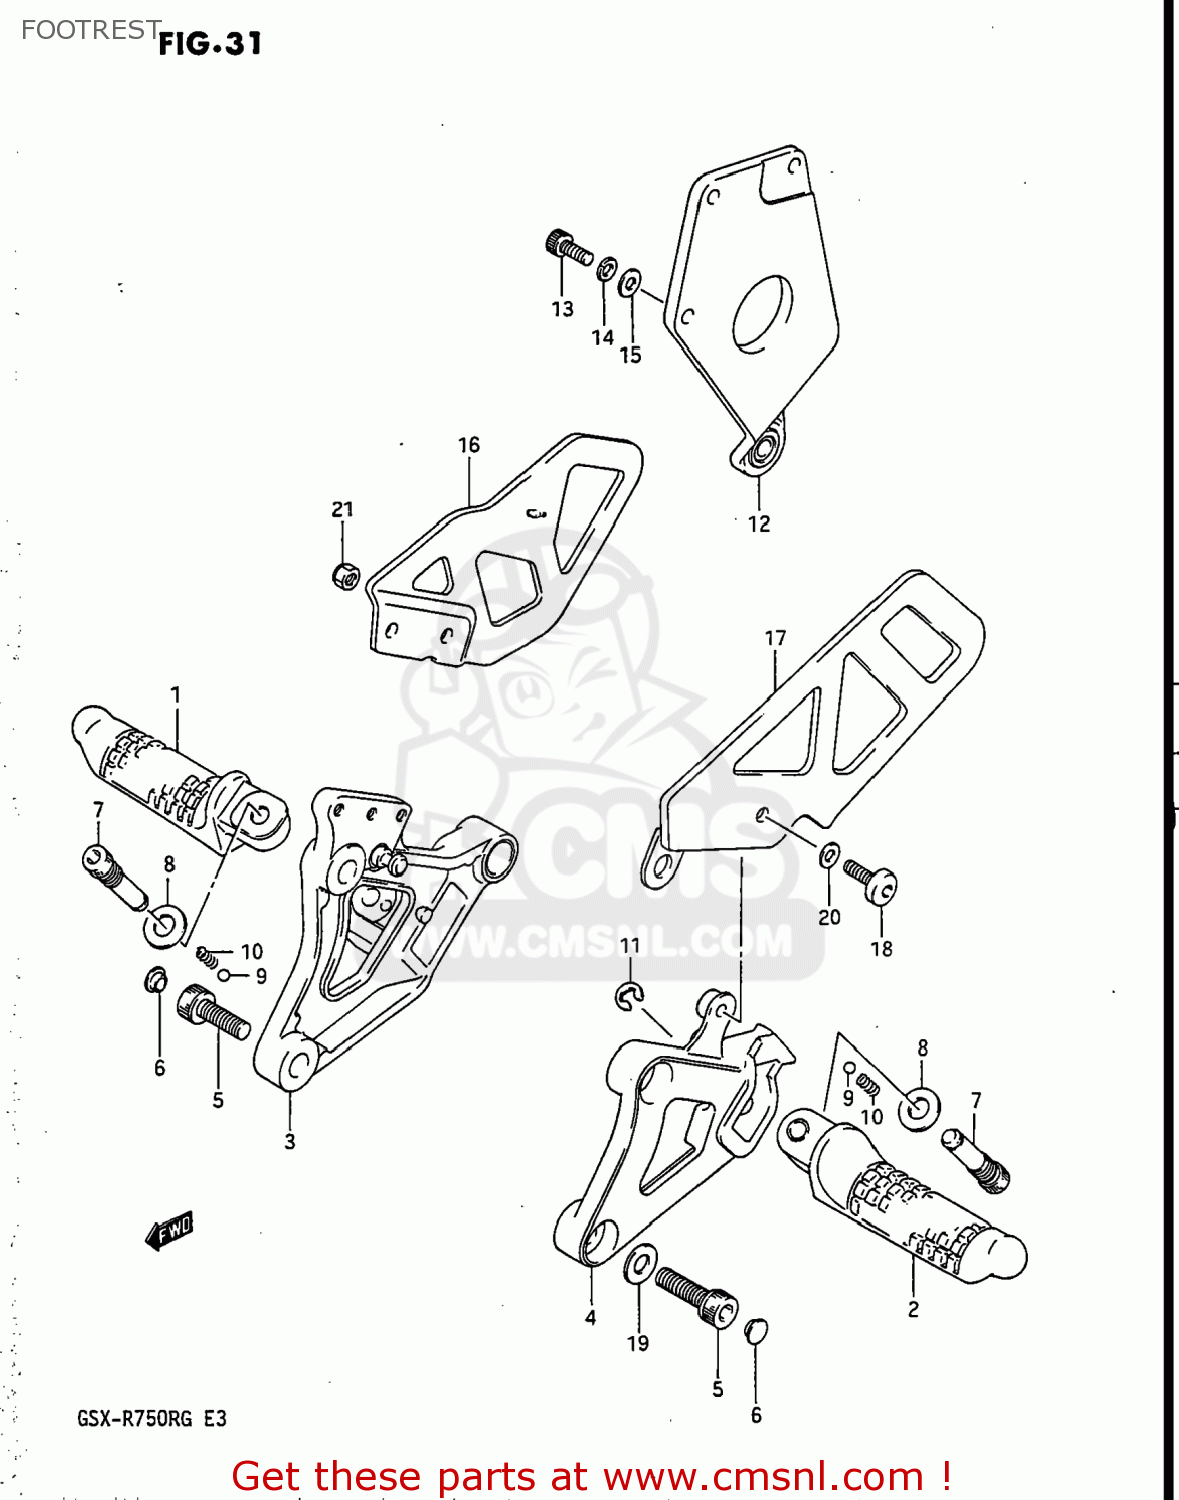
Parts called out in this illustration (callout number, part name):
1	FOOTREST ASSEMBLY,FRONT,RIGHT
2	FOOTREST ASSEMBLY,FRONT,LEFT
3	BRACKET,FOOTREST,R
4	BRACKET,FOOTREST,L
5	BOLT
6	CAP
7	BOLT,FR FOOTREST
8	PLATE,SPRING STOP
9	BALL
10	SPRING
11	E RING 6MM
12	BRACKET COMP,MUFFLER
13	BOLT
14	WASHER,LOCK
15	WASHER 6MM
16	GUARD,FRONT FOOTREST,RIGHT
17	GUARD COMP,FRONT FOOTREST
18	BOLT(6X18)
19	WASHER(10.5X20X3.2)
20	WASHER
21	NUT 6MM
